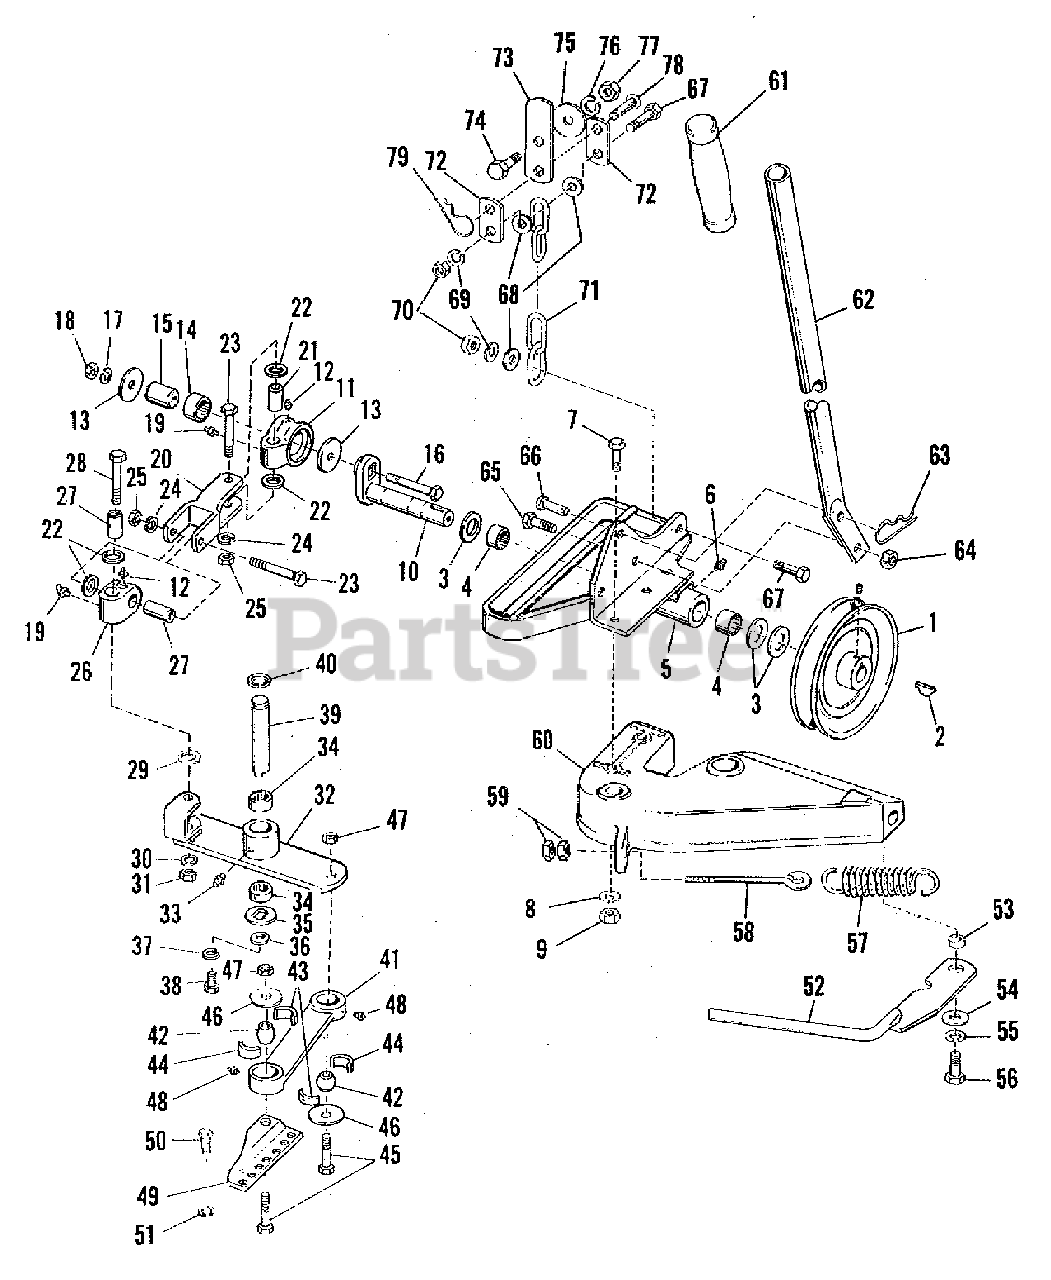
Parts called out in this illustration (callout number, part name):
1	DRIVE PULLEY
2	KEY, Hi-Pro
4	BEARING, Needle
5	BRACKET ASSEMBLY, Lift
6	FITTING, Grease
7	CAPSCREW, Hex Head, 7/16-14 x 1-1/4" Lg.
8	LOCKWASHER, 7/16"
9	NUT, Hex Full, 7/16-14
10	SHAFT, Crank
11	HOUSING, Pitman Bearing
12	FITTING, Grease
13	WASHER
14	BEARING, Needle
15	RACE, Inner, Pitman Bearing
16	CAPSCREW, Hex Head, 3/8"-16 x 2-1/4" Lg.
17	LOCKWASHER, 3/8"
18	NUT, Hex, Full, 3/8"-16
19	FITTING, Grease, 90 Degrees
20	CLEVIS ASSEMBLY, Pitman
21	BEARING, Pivot Block
23	CAPSCREW, Hex Head, 3/8"-16 x 2-1/4" Lg.
24	LOCKWASHER, 3/8"
25	NUT, Hex, Full, 3/8"-16
26	BLOCK, Pivot
28	CAPSCREW, Hex Head, 3/8"-16 x 2-1/2" Lg.
29	WASHER, Plain, 3/8"
30	LOCKWASHER, 3/8"
31	NUT, Hex, Full, 3/8"-16
32	ROCKER ARM ASSEMBLY
33	FITTING, Grease
34	BEARING, Needle
36	WASHER, Plain, 3/8"
37	LOCKWASHER, 3/8"
38	CAPSCREW, Hex Head, 3/8"-16 x 3/4" Lg.
39	SHAFT, Rocker Arm
40	RING, Retaining
41	LINK ASSEMBLY
42	BALL, Link
43	BUSHING, Ball, Half
44	BUSHING, Ball, Half
45	BOLT, Hex, Head
46	WASHER
47	NUT, Hex, Full, Lock, 3/8"-24
48	FITTING, Grease
49	HEAD, Sickle
50	CAPSCREW, Hex Head, 5/16-24 x 5/8" Lg.
51	WASHER, Lock, 5/16"
52	LATCH ASSEMBLY
53	SPACER, Latch
54	WASHER, Plain
55	LOCKWASHER, 7/16"
56	CAPSCREW, Hex Head, 7/16"-14 x 1-1/4" Lg.
59	NUT, Hex, Full, 5/16-18
61	GRIP, Handle
62	HANDLE ASSEMBLY
63	CLIP, Spring
64	NUT, Hex, Full, Lock, 3/8"-16
65	CAPSCREW, Hex Head, 3/8"-16 x 1" Lg.
67	CAPSCREW, Hex, Head, 3/8"-16 x 1" Lg.
68	WASHER, Plain, 3/8"
69	LOCKWASHER, 3/8"
70	NUT, Hex, Full, 3/8"-16
71	CHAIN, Lift
72	LINK, Mower Lift
73	SUPPORT, Chain
74	CAPSCREW, Hex Head, 3/8"-16 x 1" Lg.
75	WASHER
76	LOCKWASHER, 3/8"
77	NUT, Hex, Full, 3/8"-16
79	CLIP, Spring
